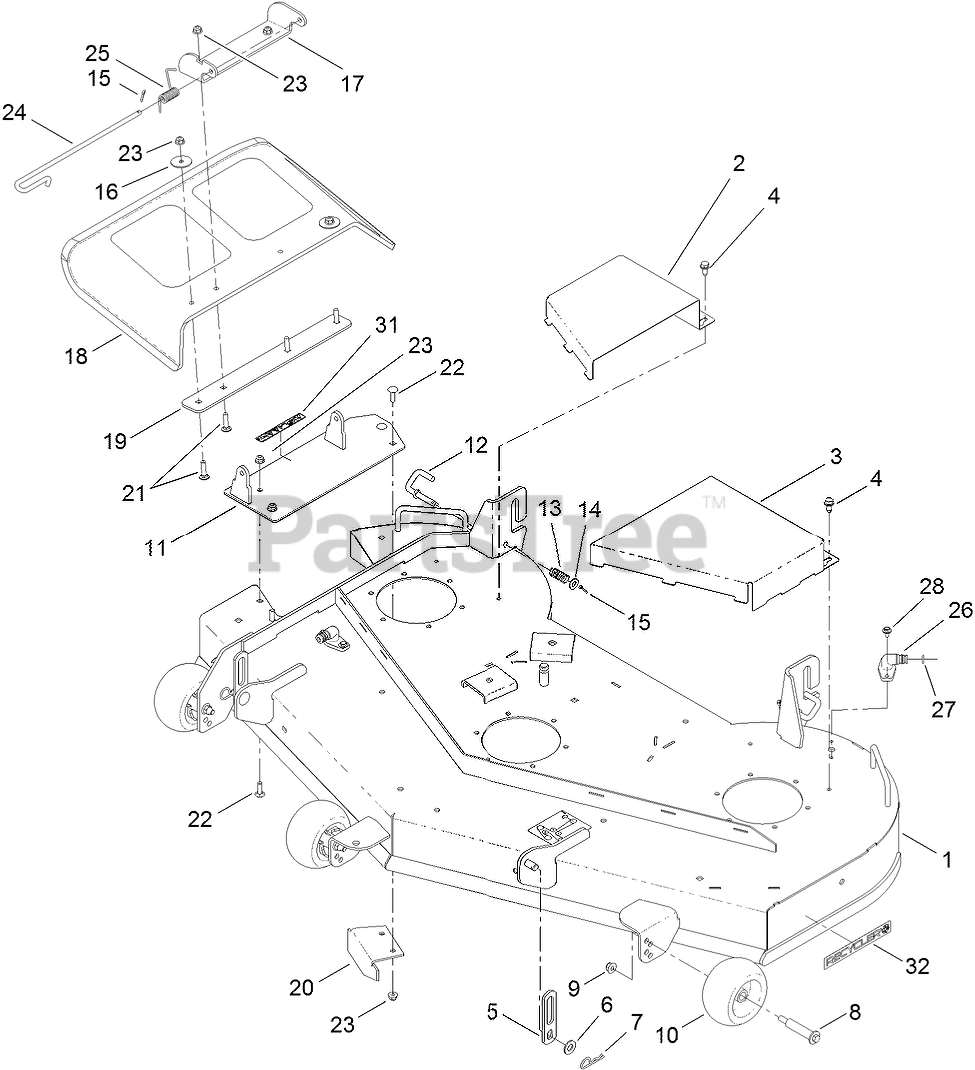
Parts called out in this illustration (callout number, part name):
1	54 INCH DECK ASM
2	COVER-BELT, RH
3	COVER-BELT, LH
4	SCREW-HWHTF
5	LINK-LIFT
6	WASHER-FLAT
7	PIN-COTTER
8	BOLT-SHOULDER
9	NUT-HF, NI
10	ROLLER-SCALP, ANTI
11	PLATE-COVER
12	PIN-LATCH
13	SPRING-COMPRESSION
14	WASHER-FLAT
15	PIN-COTTER
16	WASHER-FLAT
17	BRACKET-DEFLECTOR, UPPER
18	DEFLECTOR
19	PLATE-DEFLECTOR
20	BAFFLE-CUTOFF
21	SCREW-CARR
22	SCREW-CARR
23	NUT-HF, NI
24	PIN-CHUTE
25	SPRING-TORSION
26	FITTING-WASHOUT
27	O-RING
28	SCREW-HHFTF
31	DECAL-DANGER
32	DECAL-RECYCLER
